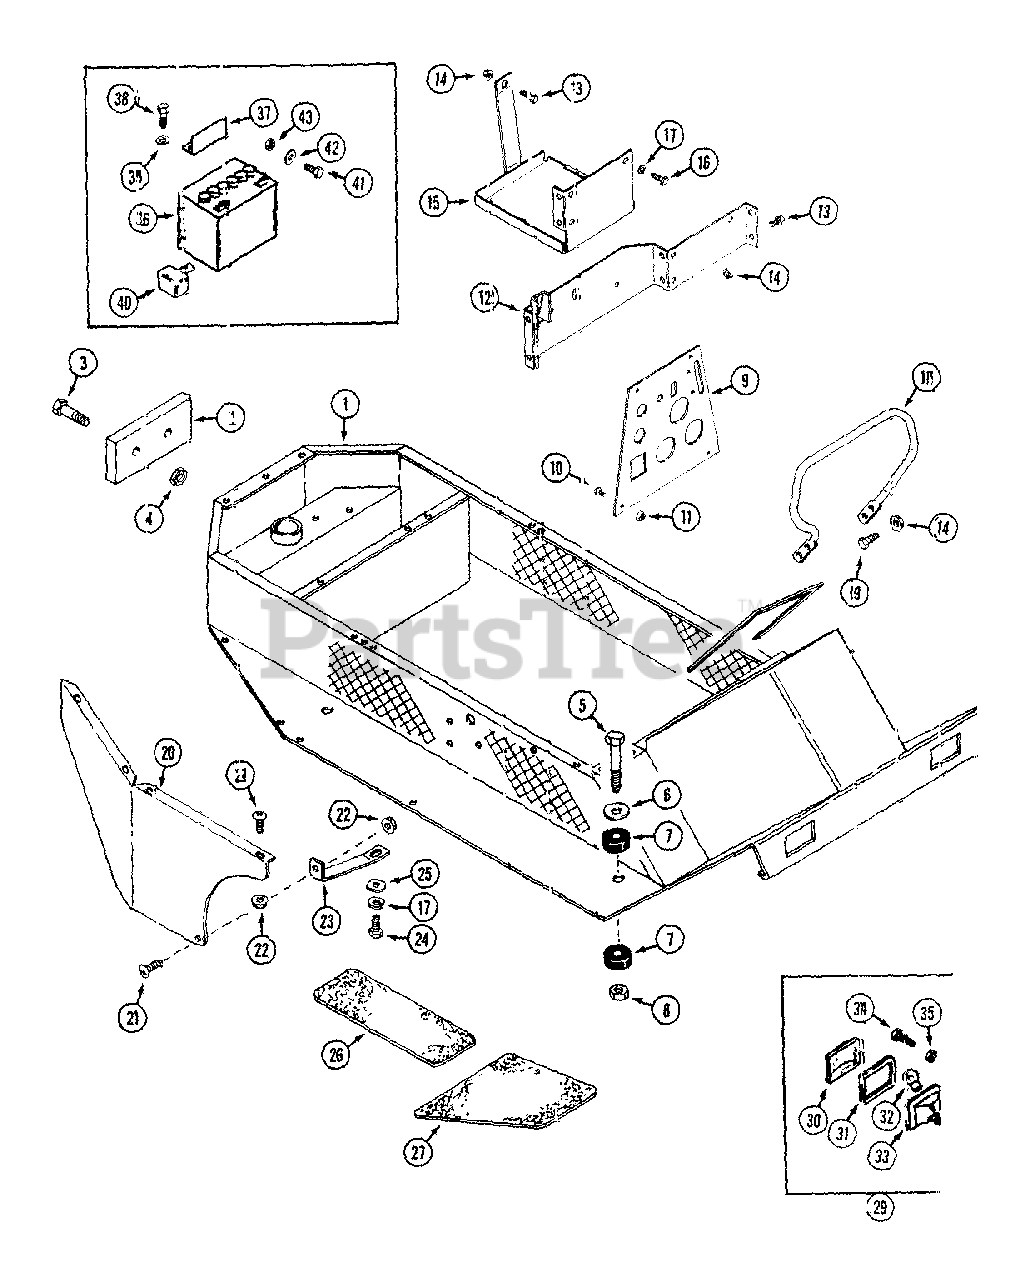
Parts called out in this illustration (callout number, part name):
1	BODY
2	PLATE - weight
3	BOLT - 3/8" - 16 x 2-3/4"
4	NUT - 3/8" - 16 Flange lock
5	BOLT - 1/2" - 13 x 5"
6	WASHER - 1/2" x 2"
7	MOUNT - rubber, body
8	NUT - 1/2" - 13 lock
9	PANEL - instrument
10	SCREW - #10 - 24 x 1/2"
11	NUT - #10 - 24 flange lock
12	CROSSMEMBER - body
13	BOLT - 5/16" - 18 x 5/8"
14	NUT - 5/16" - 18 flange lock
15	TRAY - battery
16	BOLT - 5/16" - 18 x 1/2"
17	LOCKWASHER - 5/16"
19	BOLT - 5/16" - 18 x 3/4"
20	SKIRT - fender L.H.
21	SCREW - 1/4" - 20 x 1/2"
22	NUT - 1/4" - 20 flange lock
23	BRACE - fender
24	BOLT - 5/16" - 18 x 1"
25	WASHER - 3/8" x 7/8"
26	PAD - footrest, side
27	PAD - foot, front L.H.
30	LENS
33	REFLECTOR
34	BOLT - 1/4" - 20 x 1"
35	NUT - 1/4" - 20
36	BATTERY - 12V, 450 CCA
37	RETAINER - battery
38	BOLT - 1/4" - 20 x 1-1/4"
39	WASHER - .28" x .62"
40	INSULATOR - post
41	BOLT - 1/4" - 20 x 3/4"
42	WASHER - 1/4"
43	NUT - 1/4" - 20 lock
